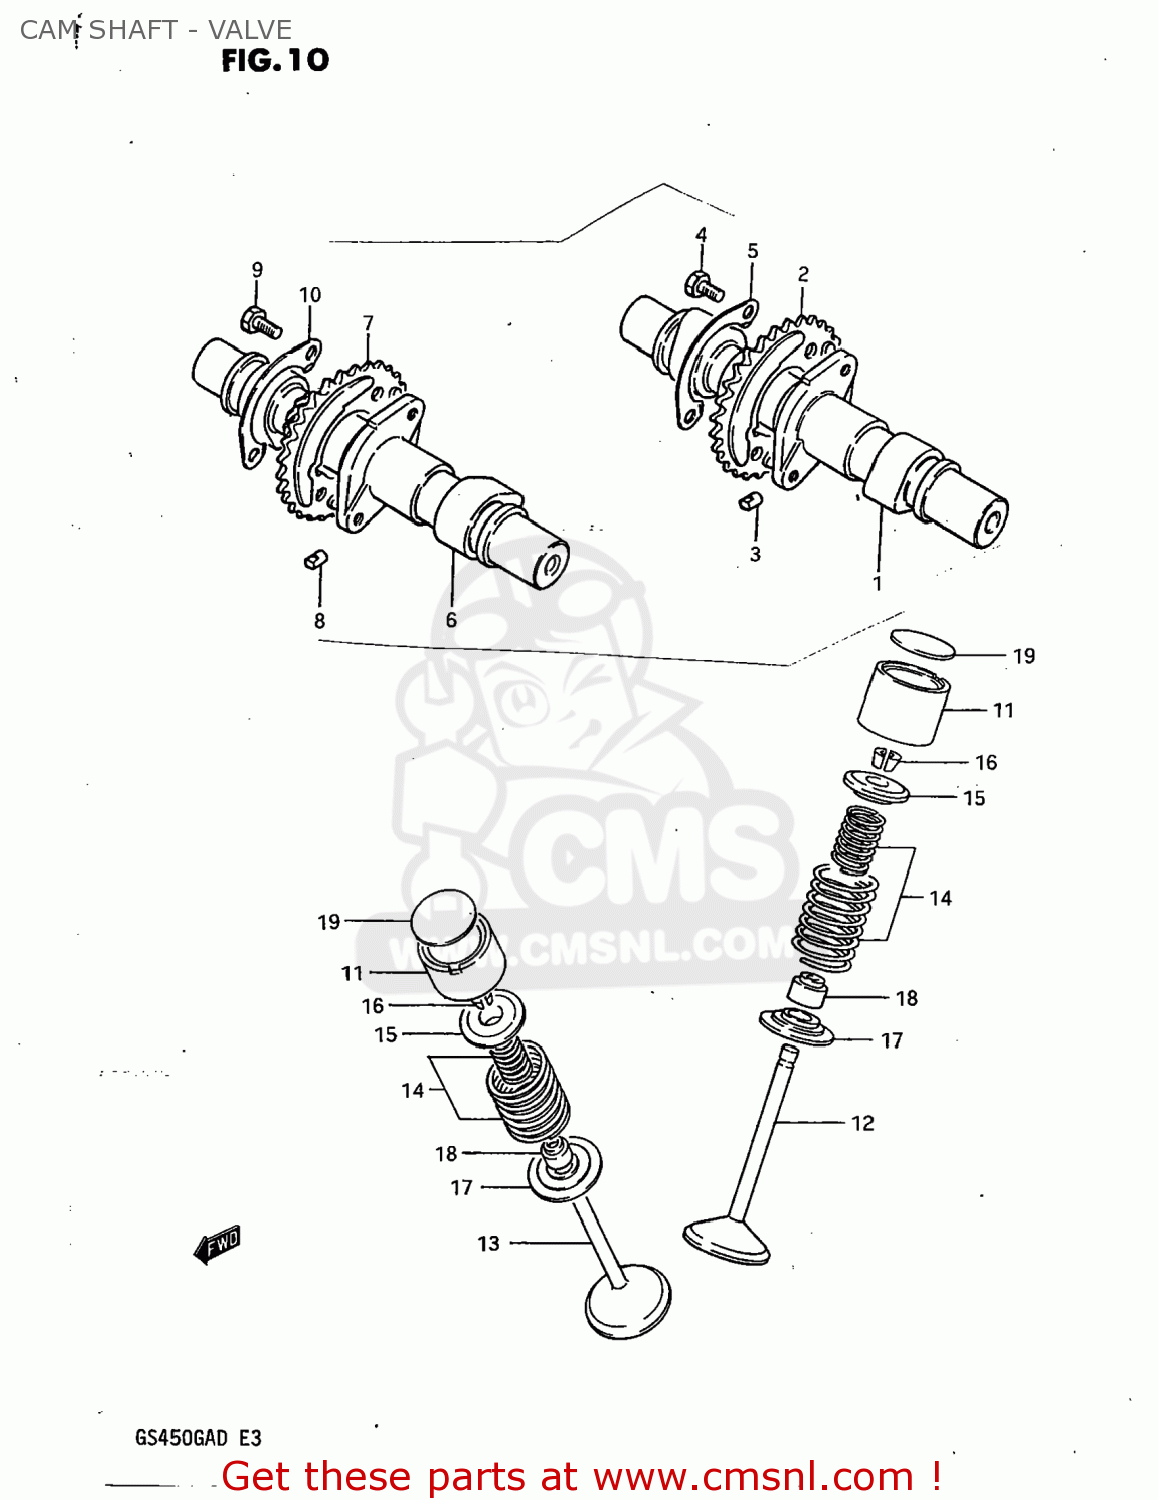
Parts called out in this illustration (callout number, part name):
1	CAMSHAFT
2	SPROCKET,CAMSHAFT
3	PIN,SPROCKET
4	BOLT(6X12.5)
5	WASHER,CAM CHAIN SPROCKET
6	CAMSHAFT,EXHAUST
7	SPROCKET,EXHAUST CAM(NT:30)
8	PIN,SPROCKET
9	BOLT(6X12.5)
10	WASHER,CAM CHAIN SPROCKET
11	TAPPET
12	VALVE,INTAKE
13	VALVE,EXHAUST
14	SPRING SET,VALVE
15	RETAINER,VALVE SPRING
16	COTTER VALVE
17	SEAT,VALVE SPRING
18	SEAL,OIL(7X14.4X9)
19	SHIM,TAPPET
20	SHIM SET,TAPPET
21	CASE
